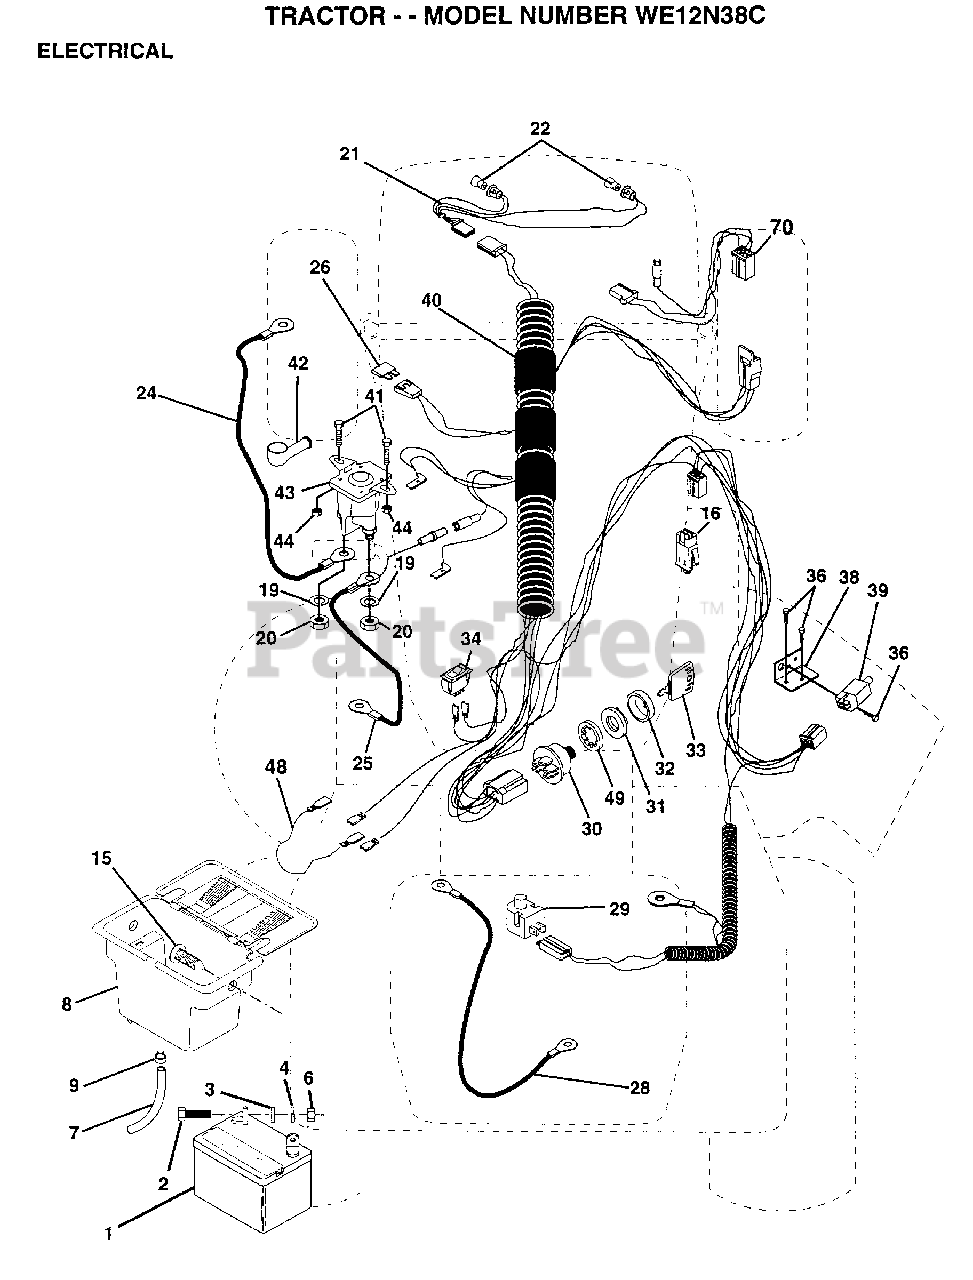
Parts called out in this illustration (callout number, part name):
2	BOLT LT
3	WASHER
4	LOCKWASHER
7	TUBE T
9	HOSE CLAMP T
15	FASTNER.SNAP-IN
16	SWITCH INTERLOCK
20	NUT
21	"HARNESS,LIGHT SOC"
22	HEADLAMP BULB
24	"CABLE T, BATTERY"
25	CABLE.BTRY.6GA.RD
26	FUSE HYT
28	CABLE T
29	SWITCH SEAT
32	COVER KEY SWITCH
33	KEY MLD GEN DELTA
34	SWITCH LT
36	SCREW
38	BRACKET SWITCH IN
39	SWITCH INTERLOCKT
40	HARNESS.IGN.DASH.
41	BOLT HXHD FIN
44	NUT HXKEP 1/4X20
48	ADAPTER AMMETER
49	WASHER PINNED
70	HARNESS ENG DUAL
